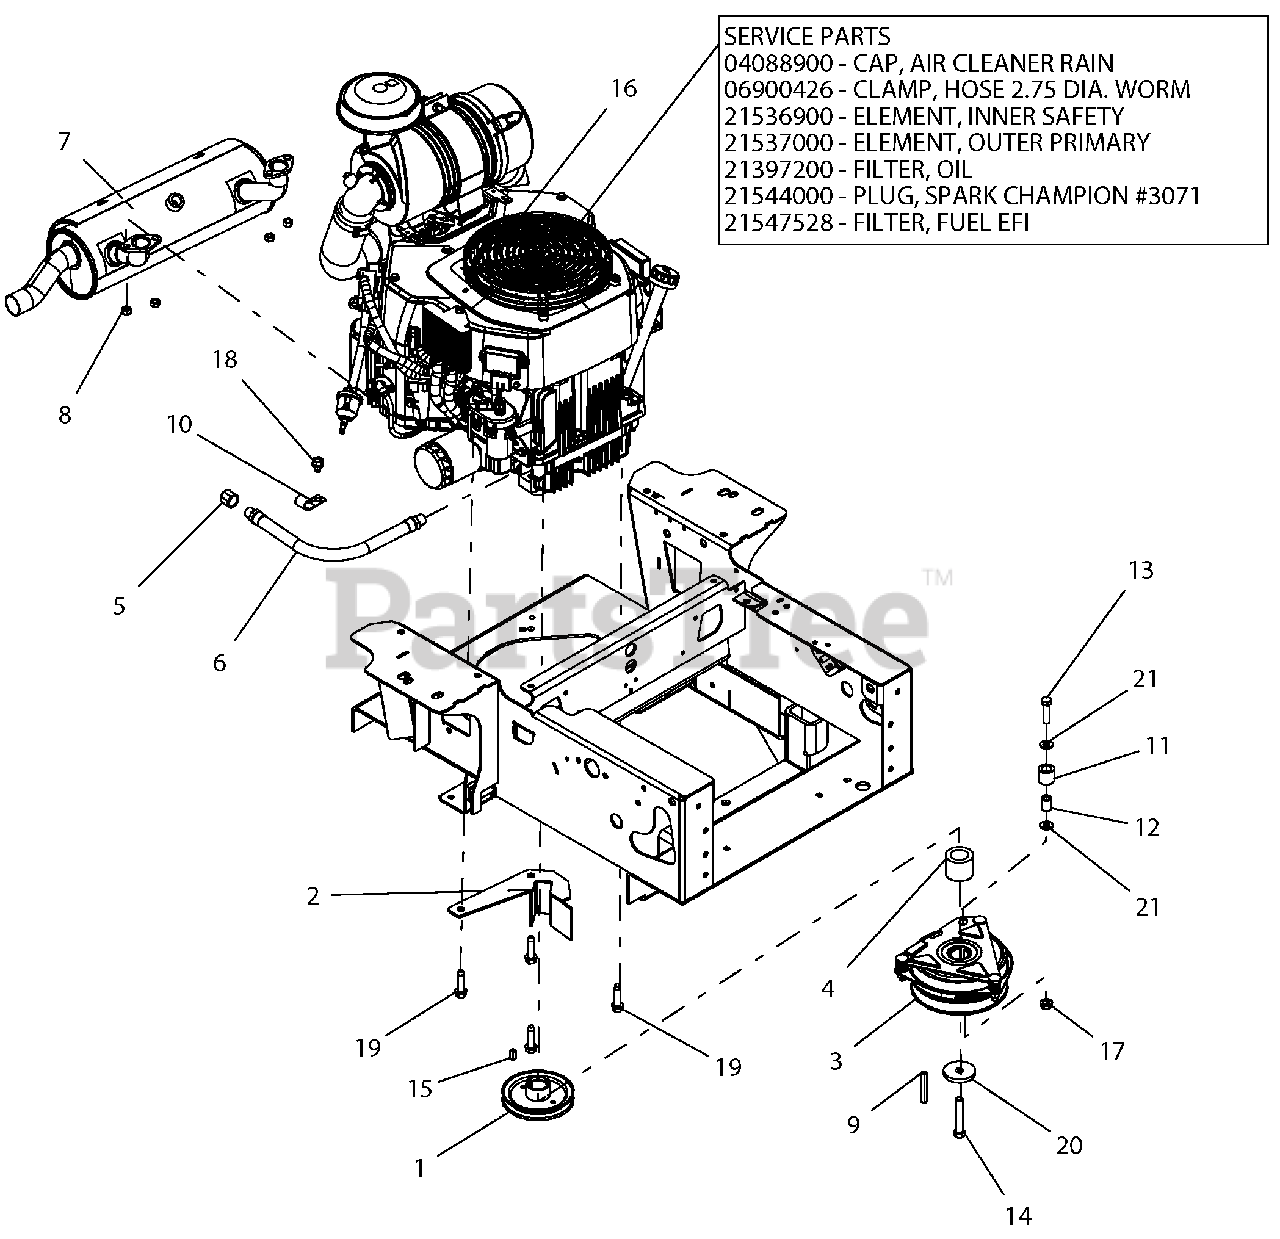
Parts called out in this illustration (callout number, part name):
1	PULLEY, 4.50 OD X 1.127 ENGINE-BLACK
2	WMT, 100I CLUTCH STOP - BLK
3	CLUTCH, OGURA GT2.5-FE02
4	SPACER, 1.125 X 1.75 X 1.40
5	PIPE, CAP 3/8 NPT FEMALE
6	HOSE, HYD .38-11-OK M6N0-M6N0
7	MUFFLER, KOHLER EFI
8	NUT-LK-TOP M8-1.25 YWZC
9	KEY, .25X.25X2.25
11	BUMPER, RUBBER .62 X 1.0 X .88 LG
12	BUSHING, SLV .407X.625X.813
13	BLT-HEX .38-16X1.50 GR5 YWZC
14	BLT-HEX .44-20X2.50 GR5 EP80 YWZC
15	KEY-SQ .250X.250X.625
16	ENGINE, KOHLER EFI ECV740
17	NUT, LK-TOP-FLG .38-16 YWZC
18	SCR-TAP .38-16X.50 HWH TR YWZ
19	SCR-TAP .38-16X1.50 HWH TR YZ
20	WSHR-FL-STL .469X2.00X.25 YWZC
21	WSHR-FL-STL.406X.812X.065 YWZ
